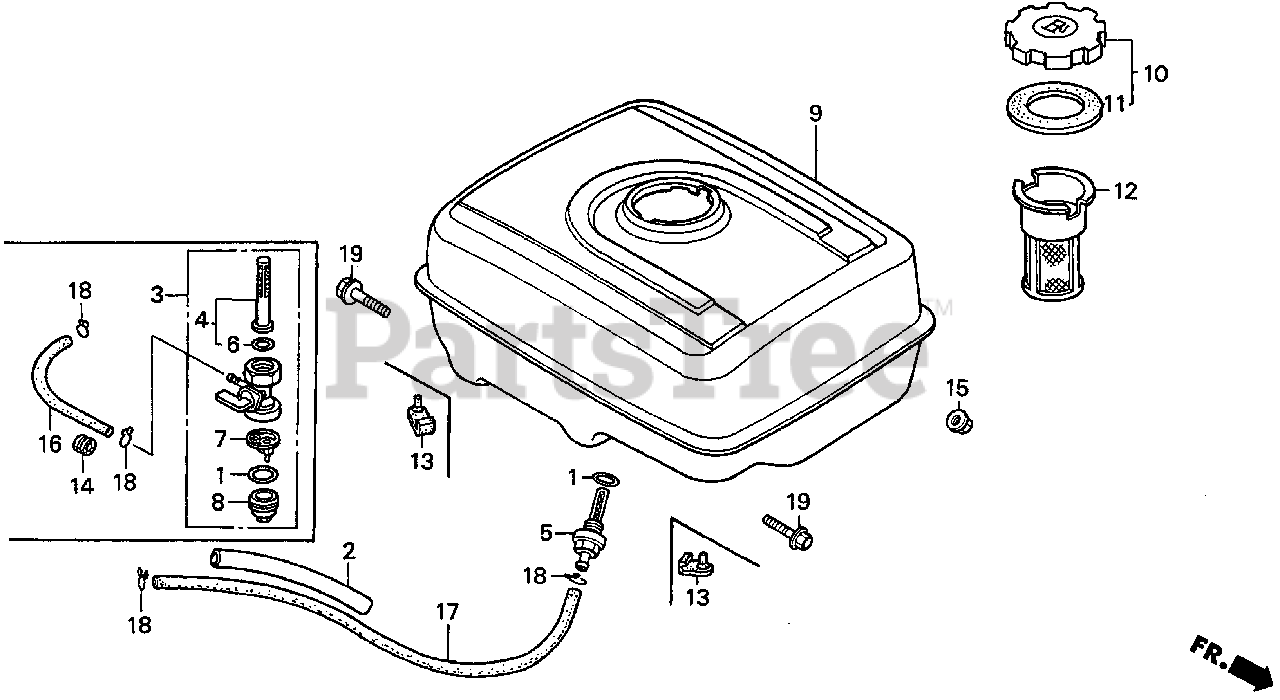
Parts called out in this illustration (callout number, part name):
1	GASKET, FUEL STRAINER CUP
2	RUBBER, SUPPORTER (107MM)
5	JOINT, FUEL TANK
9	TANK, FUEL *NH31* (MCKINLEY WHITE)
10	CAP, FUEL FILLER
11	GASKET, FUEL FILLER CAP
12	FILTER, FUEL
15	NUT, FLANGE (8MM)
17	BULK HOSE, FUEL (4.5X3000) (4.5X235)
18	CLIP, TUBE (B8)
19	BOLT, FLANGE (8X25)
